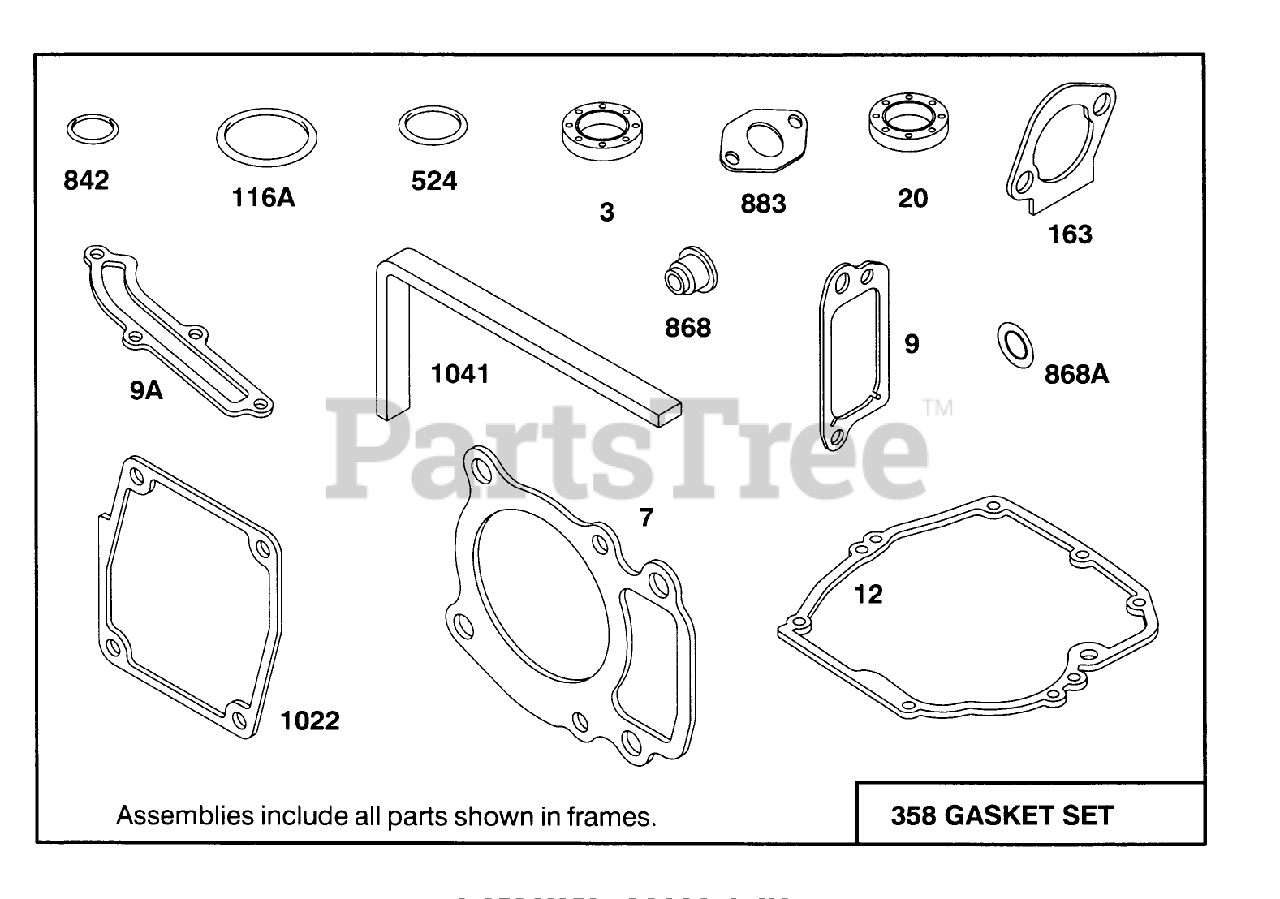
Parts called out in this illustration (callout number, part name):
104	FLOAT HINGE PIN
116	SEALING GASKET
118	VALVE KIT - NEEDLE
121	CARBURATOR OVERHAUL KIT
122	ADAPTER ASSEMBLY
134	Valve-Float (includes Seat)
137	FLOAT BOWL GASKET
634	SEAL WASHER
977	CARBURATOR GASKET SET
1039	FLOAT LIMITER
